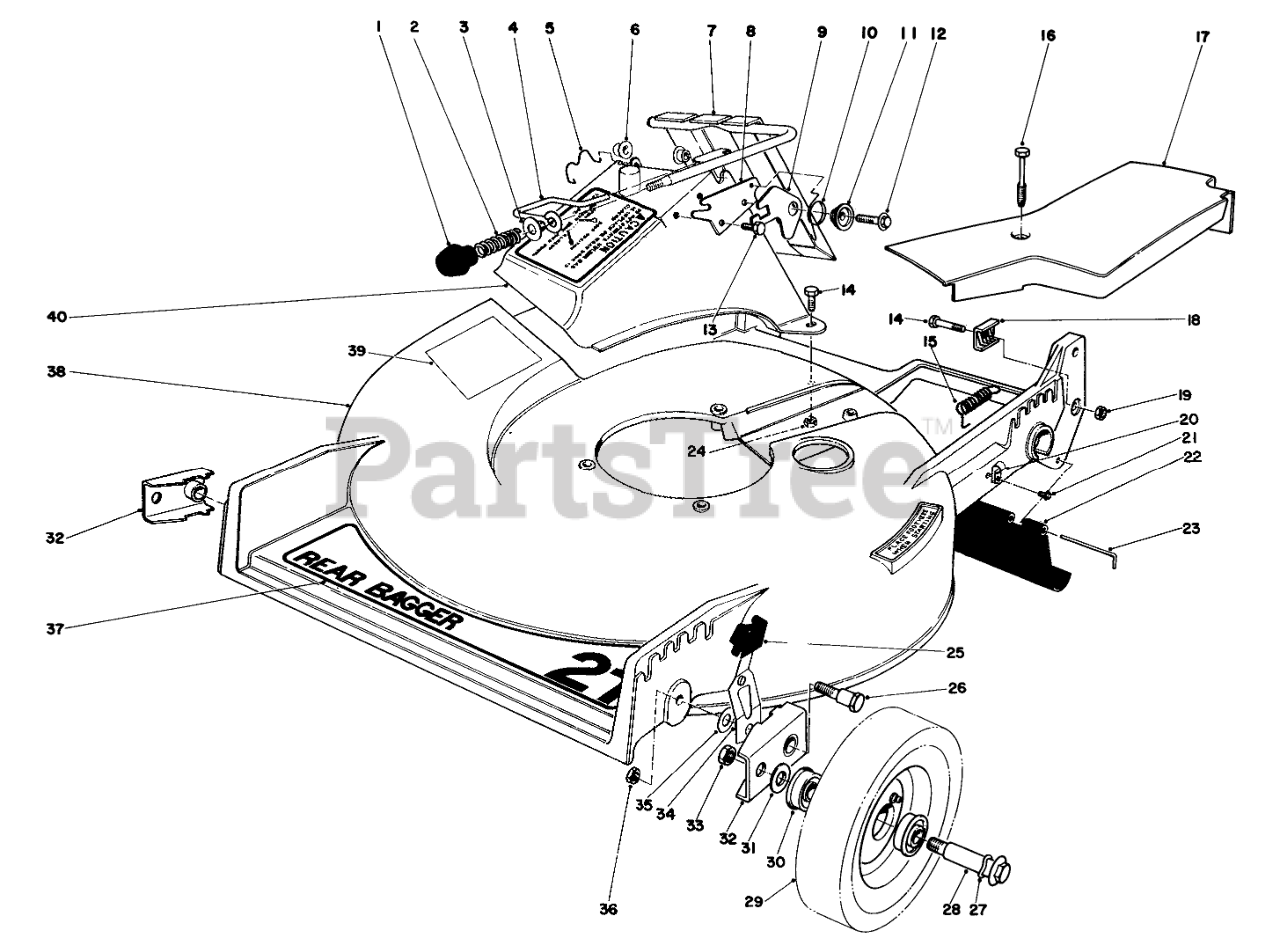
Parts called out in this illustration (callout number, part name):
2	COMPRESSION SPRING
3	WASHER-FLAT
4	DOOR LATCH
5	DOOR RETAINER
6	BUSHING-NYLON
7	DOOR & HANDLE WA
8	DOOR LATCH PLATE
9	SAFETY LATCH
10	TORSION SPRING
11	DOOR SPACER
12	Screw
13	SCREW-HWH
14	SCREW-HH
15	IDLER SPRING
16	SCREW-HHFTF
17	Belt Cover
18	CLAMP-CABLE
19	NUT-JAM
20	CLAMP-NYLON
21	SCREW-HWH
22	SHIELD - TRAILING
23	Rod Shield
25	KNOB-ARM
26	PIVOT SCREW
27	SPRING WASHER
29	Wheel & Tire Assembly (Incl. Ref. #30)
30	BEARING-BALL
31	WASHER
32	Pivot Arm
33	Nut
34	Spring Arm
35	WASHER-PIVOT
36	Nut
37	Decal-Deck
38	Housing
39	Decal Caution (German)
40	DISCHARGE CHUTE B
